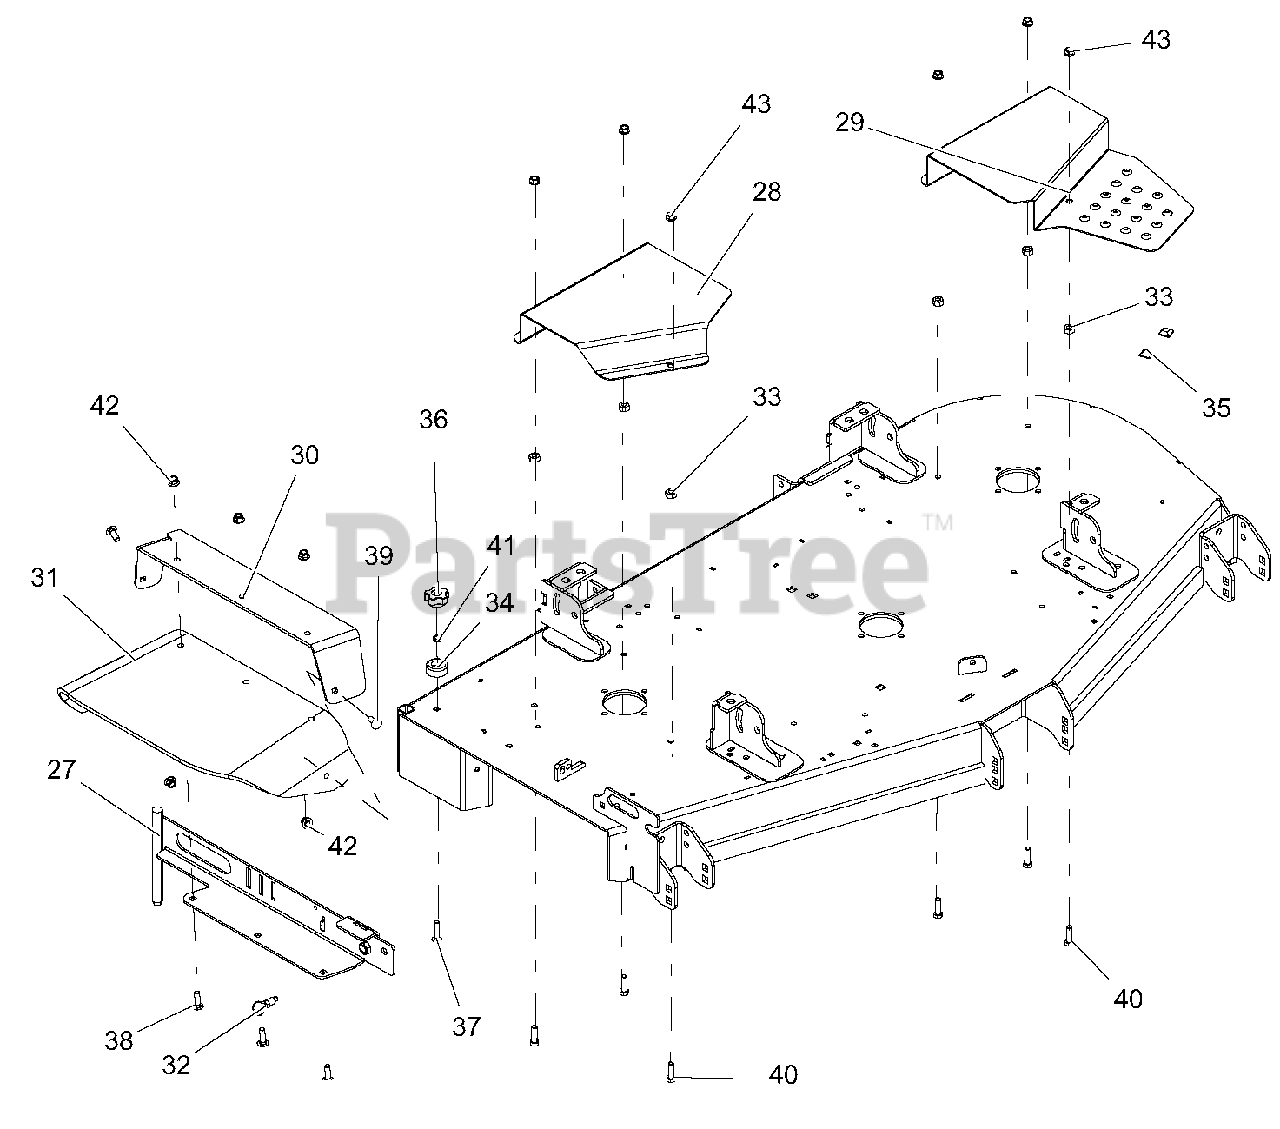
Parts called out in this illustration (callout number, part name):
27	WLDMT, 52"-60" DISCH CHUTE MTG-RED
28	GUARD, 60"-66" RH DECK BELT-RED
29	GUARD, 60" LH DECK BELT-W/STEP-RED
30	SUPPORT, CHUTE MOUNTING BRACKET-RED
31	CHUTE, RUBBER DISCHARGE
32	PULL PIN,.50-13THDX.310 PLNGR
33	NUT-HEAVY HEX .38-16 YWZC
34	BUMPER, RECESSED 1.50 X .63 W/.31 HOLE
36	KNOB, CLAMPING
37	@BLT-RDHDSQNK .31-18X1.50 G5 YWZC
38	@BLT-RDHDSQNK .38-16X1.25 G5 YWZC
39	@BLT-RDHDSQNK .38-16X1.00 G5 YWZC
40	BLT-HEX .38-16X1.25 GR5 YWZC
41	@NUT-LK-CTR .31-18 YWZC
42	NUT-LK-NYL-FLG .38-16 YWZC
43	@NUT-SPNLK-FLG .375-16 YWZC
